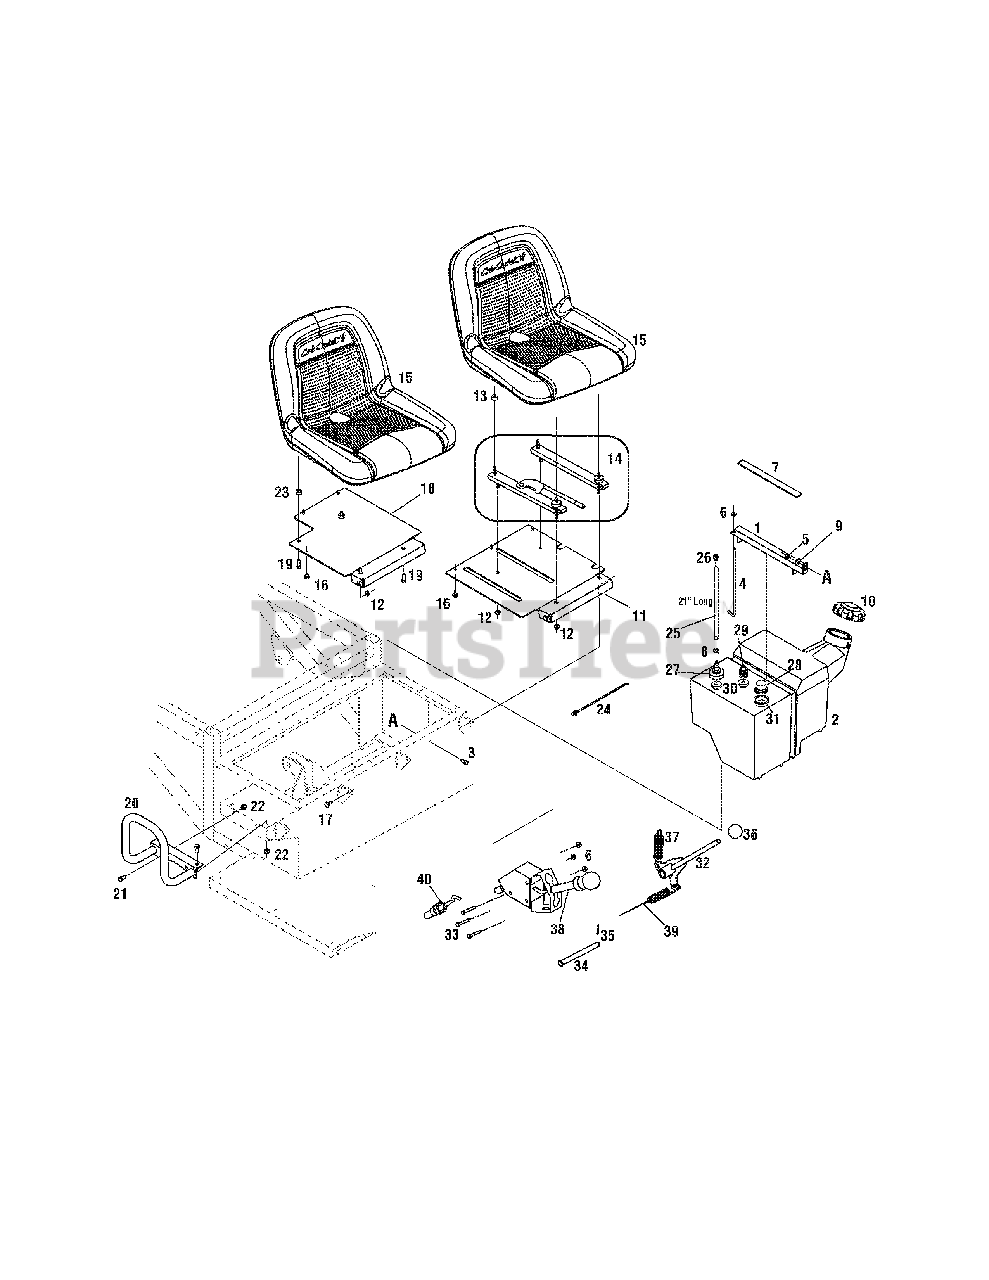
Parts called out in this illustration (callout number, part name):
1	Bracket Assembly, Fuel Tank
2	Tank Assembly, Fuel (Incl. valve, grommets, cap. Switch & fitting)
3	Hex Screw, 5/16-18 x .75
4	Hold-down Rod, Fuel Tank
5	Sems Nut, 5/16-18
6	Nut, Flange Lock, 1/4-20
7	Gasket, Fuel Tank (11")
8	Clamp, Hose
9	Washer, .349 x .879 x .063
10	Cap, Fuel
11	Plate, Seat, LH
12	Nut, Flange Lock, 5/16-18, Gr5
13	Spacer, Seat
14	Track Assembly, Seat
16	Bumper
17	Shoulder Screw,.435 x.178-5/16 x.56
18	Plate, Seat, RH
19	Hex Screw, 5/16-18 x 1.0
22	Nut, Hex Lock Nylon, 3/8-16
23	Spacer,.315 x.750 x.375
24	Cable Tie
25	Fuel Line Hose
27	Fuel Return Fitting
28	Fuel Tank Gauge
29	Fuel Tank Shut Off Valve
30	Grommet
32	Diff Lock Shift Assembly
33	Hex Screw, 1/4-20 x 2.25
34	Clevis Pin
35	Cotter Pin
37	Extension Spring
38	Shifter Control
39	Diff Lock Control Cable
40	Shift Panel Control Cable
